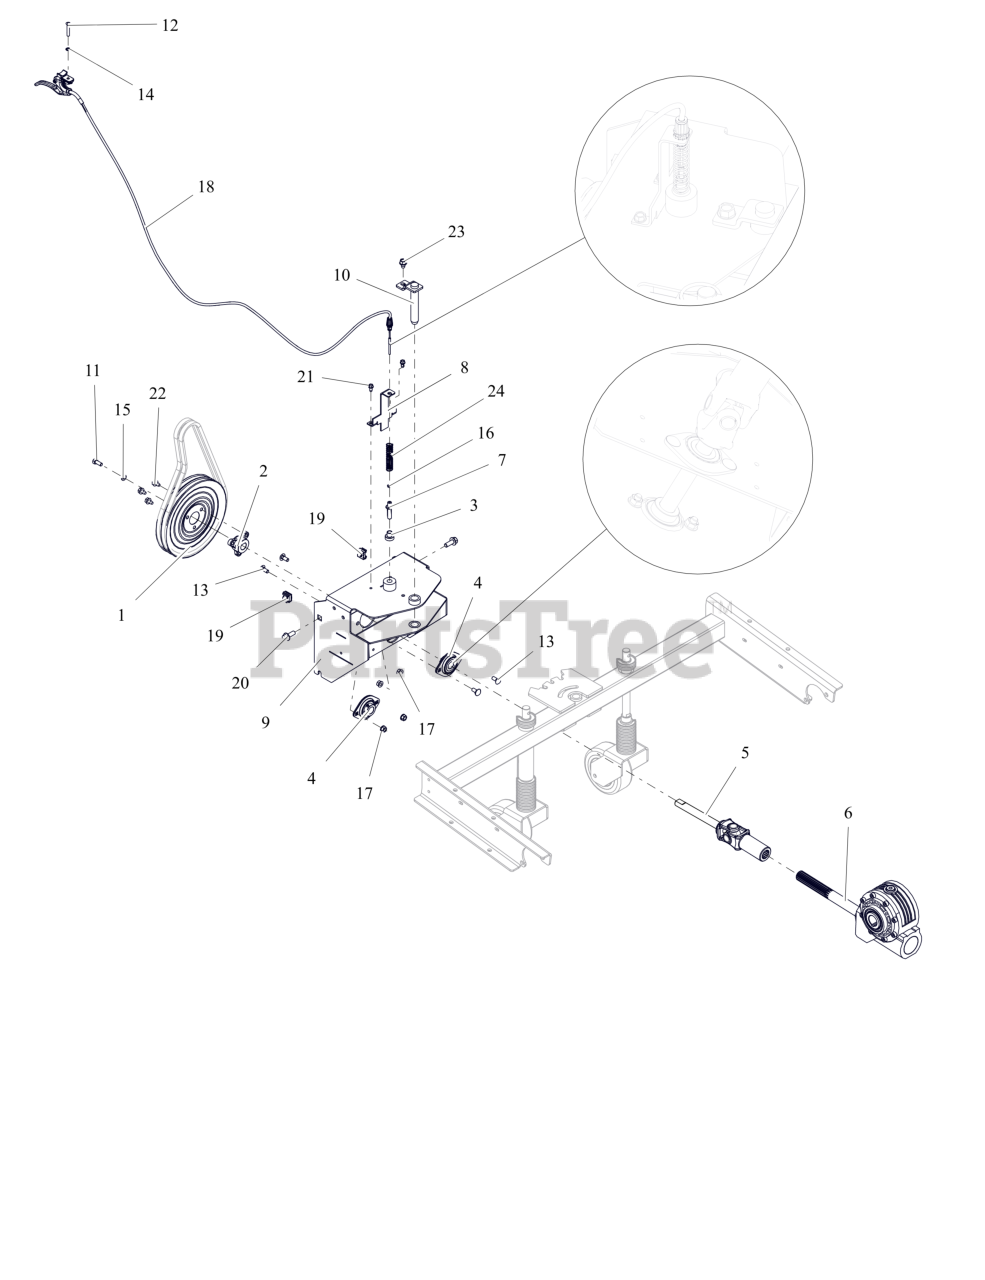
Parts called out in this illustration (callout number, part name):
1	PULLEY, SPIN FORM DUAL GROOVE
2	PULLEY HUB, BOLT-ON D-BORE .75
3	SPACER -FLANGED .390X.500X.781
4	BEARING, 2 BOLT FLANGE -.75 ID
5	DRIVELINE, SERIES 07 (U-JOINT)
6	GEARBOX, WORM - 8.25:1
7	PIN, ADJUSTABLE ANGLE BRUSH
8	BRKT, PIN HOLDER
9	ADAPTER, BRUSH
10	WLDMT, BRUSH PIN
11	BLT, HEX .31-24X.750 G5 ZCC
12	SCR,OVAL .25-20X1.50 ZCC
13	BLT,RHSN .31-18X.75 G5 ZCC
14	WSHR-LK-INT .250 TH TYA
15	WSHR, LK-HVY .312X.097 ZCC
16	NUT, HEX #10-24 ZCC
17	NUT-LK-TOP-FLG .312-18 GF ZCC
18	CABLE, REMOTE BRUSH LOCK
19	NUT-RETNR .38-16 TINRMAN
20	BLT, SERHFWH .38-16X1.00 ZCC
21	SCR-TAP .25-20X.50 HWH ZCC
22	SCR,TAP .312-18X.50 HWH TR ZCC
23	SCR,TAP .375-16X.50 HWH TR ZCC
24	SPRING, COMPRESSION
